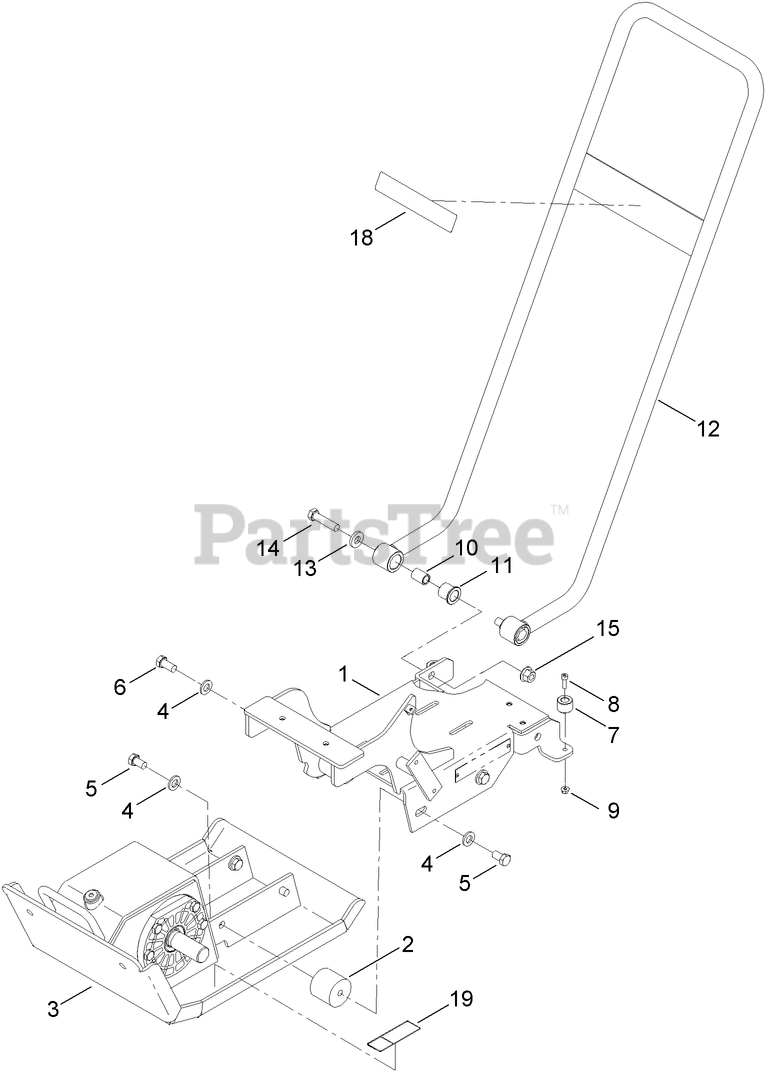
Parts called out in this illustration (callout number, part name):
1	DECK-ENGINE
2	MOUNT-SHOCK
3	BASE ASM
4	WASHER-FLAT
5	SCREW-HH
6	SCREW-HH
7	SPACER-STOP, HANDLE
8	SCREW-HSH
9	NUT-HF
10	SPACER-HANDLE, PIVOT
11	BUSHING-HANDLE, MAIN PLATE
12	HANDLE-MAIN
13	WASHER-FLAT
14	SCREW-HH
15	NUT-LOCK, HHF
19	DECAL-WARNING, SHIELDS
